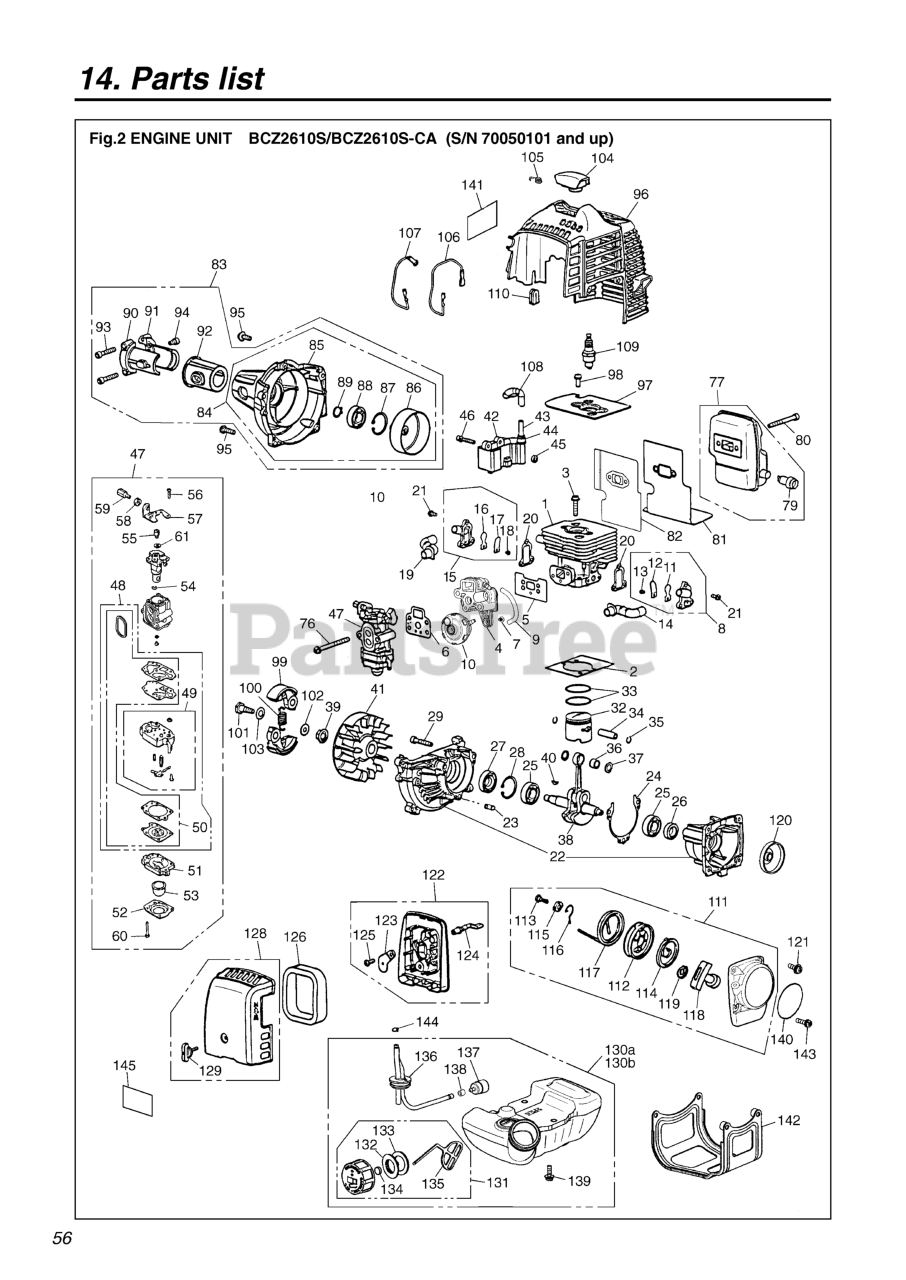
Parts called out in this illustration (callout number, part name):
1	CYLINDER
2	GASKET
3	BOLT
4	INSULATOR
5	GASKET
6	GASKET, CARBURETOR
7	SCREW
8	REEDVALVE (S) ASSY
9	TUBE
10	PUMP ASSY
11	REEDVALVE
12	STOPPER
13	SCREW, M3 x 8
14	PIPE, AIR S
15	REED VALVE ASSY-F
16	REEDVALVE
17	STOPPER
18	SCREW, M3 x 8
19	PIPE, AIR F
20	GASKET, VALVE
21	SCREW
22	CRANKCASE COMP
23	PIN
24	GASKET
25	BEARING
26	SEAL
27	SEAL
28	RING
29	BOLT
32	PISTON
33	RING
34	PIN
35	RING
36	BEARING
37	WASHER
38	CRANKSHAFT COMP
39	NUT
40	KEY
41	ROTOR
42	COIL ASSY
43	CORD
44	CAP
45	SPACER
46	BOLT TORX
47	CARBURETOR ASSY
48	REBUILD KIT
49	BODY ASSY
50	GASKET KIT
51	BODY
52	COVER
53	PUMP
54	RING
55	SWIVEL
56	SCREW
58	NUT
59	SCREW
60	SCREW
61	WASHER
76	SCREW
77	MUFFLER ASSY
79	ARRESTER
80	BOLT
81	GASKET
82	PLATE, MUFFLER
83	COVER ASSY
84	COVER COMP
85	COVER FAN
86	DRUM
87	RING
88	BEARING
89	SNAP RING
90	BRACKET-A
91	BRACKET-B
92	CUSHION
93	BOLT
94	BOLT
95	BOLT, TORX
96	COVER, ENGINE
97	PLATE
98	BOLT
99	SHOE
100	SPRING
101	SCREW
102	WASHER
103	WASHER
104	CAP
105	SPRING
106	CORD
107	CORD
108	TUBE
109	SPARK PLUG
110	GROMMET
111	RECOIL ASSY
112	REEL
113	SCREW
114	SPRING, SPIRAL
115	COLLAR
116	ARM
117	ROPE
118	KNOB
119	PLATE, STOPPER
120	PULLEY
121	BOLT
122	BODY ASSY
123	PLATE, CHOKE
124	LEVER, CHOKE
125	SCREW
126	ELEMENT
128	COVER ASSY
129	KNOB
130A	TANK ASSY
131	CAP ASSY
132	HOLDER ASSY
133	PACKING
134	FILTER
135	STOPPER
136	PIPE COMP
137	FILTER ASSY
138	CLIP
139	SCREW
140	LABEL, RECOIL
141	LABEL, COVER
142	GUARD
143	BOLT
144	CLIP
